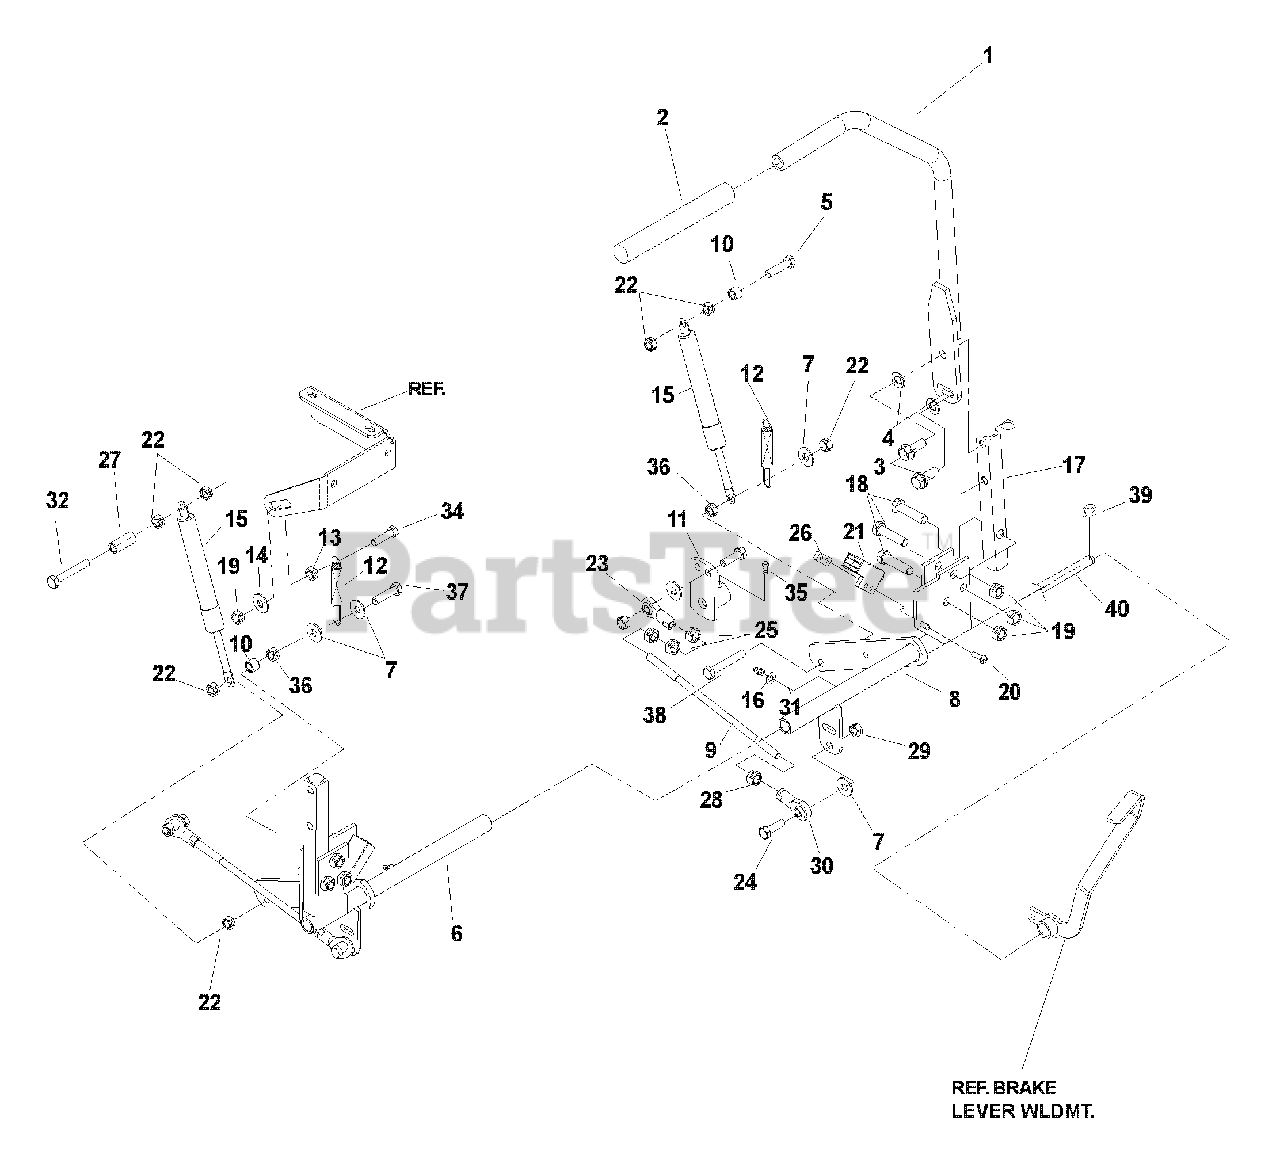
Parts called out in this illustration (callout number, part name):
1	CONTROL LEVER WLDMT
3	HCS 3/8C X 1
4	3/8 DISC SPRING WASHER
5	HCS 5/16C X 1 1/2
6	CONTROL WELDMENT, RIGHT
7	WASHER 5/16 FLAT
8	CONTROL WELDMENT, LEFT
9	PUMP CONTROL LINK
11	CONTROL ARM, PUMP
13	3/8C WHIZ NUT
14	WASHER 3/8 FLAT
16	ZERK
17	CONTROL ARM
18	HCS 3/8C X 1 3/4
19	NUT, 3/8C, NYLOC
20	SCREW 310-24 X 5/8
22	NUT, 5/16C, CENTERLOCK
23	BALL JOINT, RIGHT
24	HCS 5/16C X 1 1/4
25	NUT, 5/16-24
26	TAPPED PLATE
28	NUT, 5/16F, LEFT HAND
29	NUT, 5/16C, NYLOC
30	BALL JOINT, LEFT
32	HCS 5/16C X 2
34	HCS 3/8C X 2 1/2
35	SCREW, 5/16C X 5/8, SET
36	NUT 5/16C, WHIZ
37	BOLT, 5/16C X 2 1/4, TAP
38	BOLT, 5/16C X 1 1/4, TAP
39	E-RING, 1/2
40	CONTROL SHAFT
